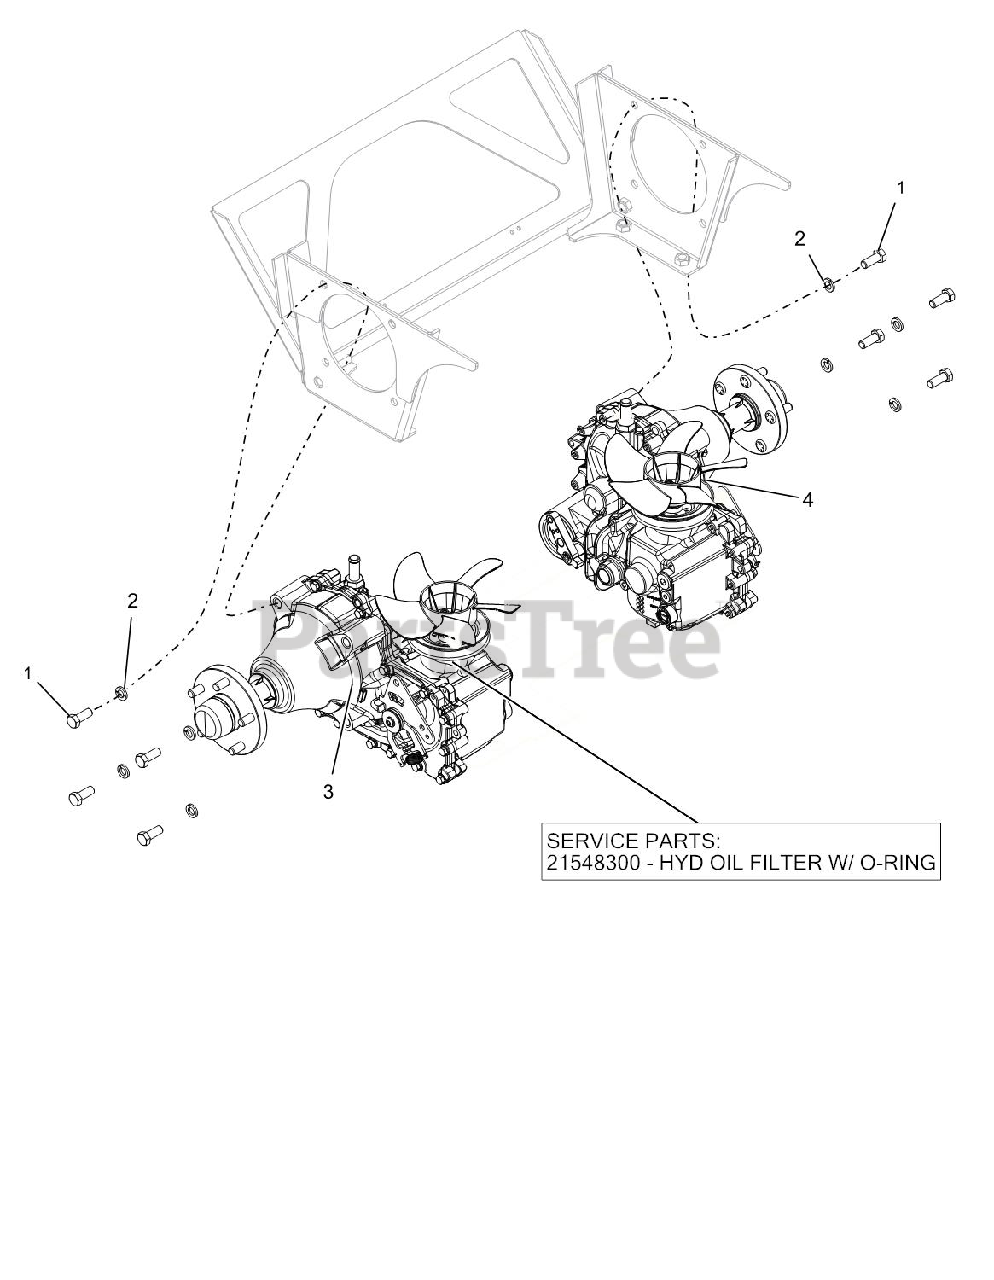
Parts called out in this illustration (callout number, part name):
1	BLT-HEX .50-13X1.25 GR5 YWZC
2	WSHR-LK .50X.125 REG YWZC
3	TRANS, RH HG ZT-5400
3	FILTER,HYD OIL W/ORING ZT-54OO
4	TRANS, LH HG ZT-5400
